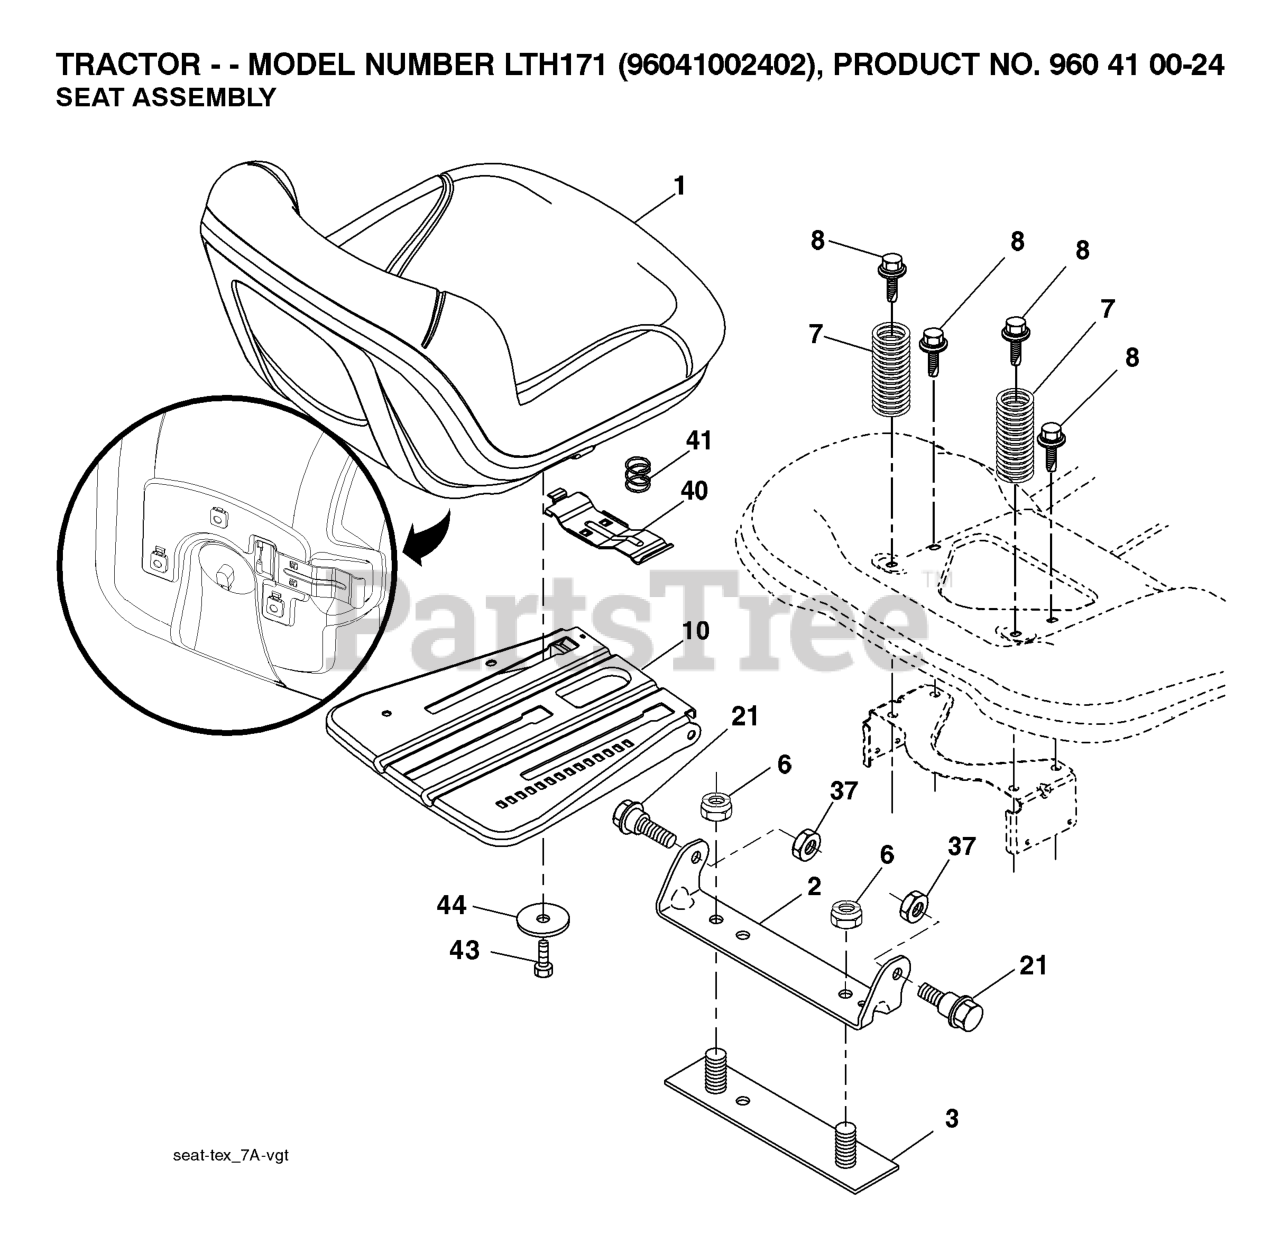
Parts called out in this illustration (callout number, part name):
1	SEAT.TH130.GRY.MILSCO.
2	BRKT.PIVOT.FENDER
3	STRAP
6	NUT
7	SPRING COMPRESSION
8	BOLT.5/16-18UNCX3/4 W/SEMS.BLK
10	PAN.ASM.SEAT.3PT
21	BOLT.SHOULDER.5/16-18
37	NUT.71038.31-18.HEX.NYLOCK
40	HANDLE.SLIDE.SEAT.TEX.BLACK
41	SPRING.LATCH.SEAT.TEX
44	WASHER 13/32 X 2-3/8 X 12GA
